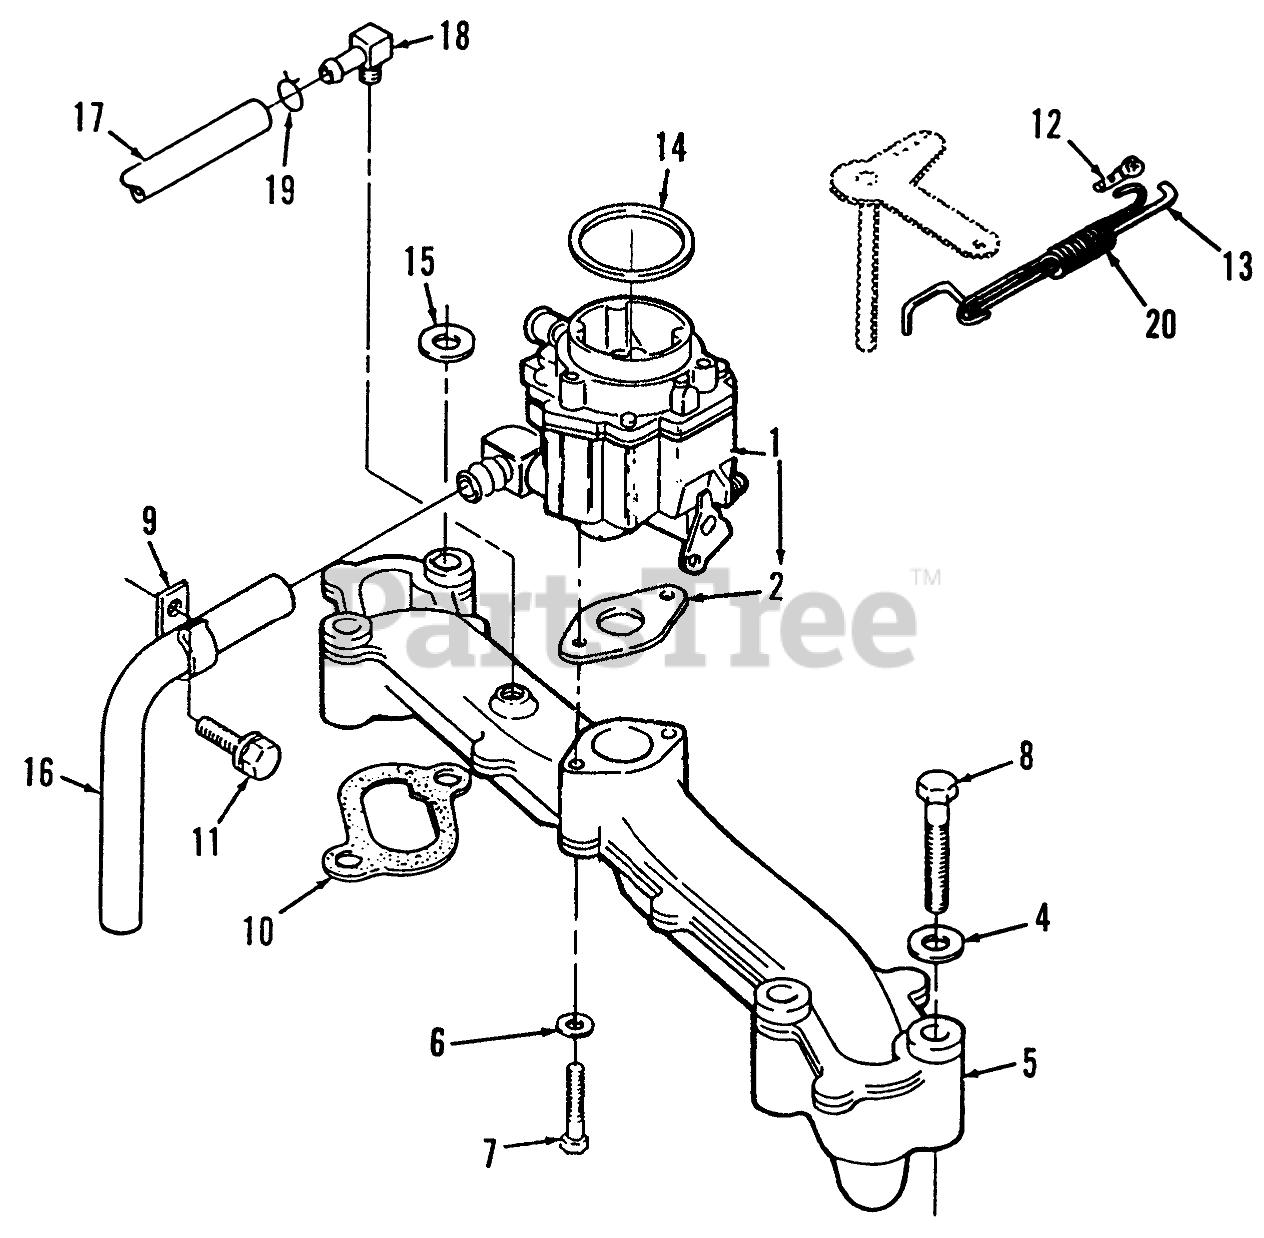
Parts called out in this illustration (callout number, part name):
1	Carburetor (Includes Mounting Gasket, Elbow and "O" Ring) See section 9-17 for complete carburetor breakdown
2	Gasket
4	Nut-M8
5	Intake Manifold
6	Nut-M8
7	Screw 5/16-18 1-3/4
9	FLAT WASHER
10	Gasket
11	Bolt
13	Governor Control Rod
15	FLAT WASHER
20	Spring-Governor Rod
